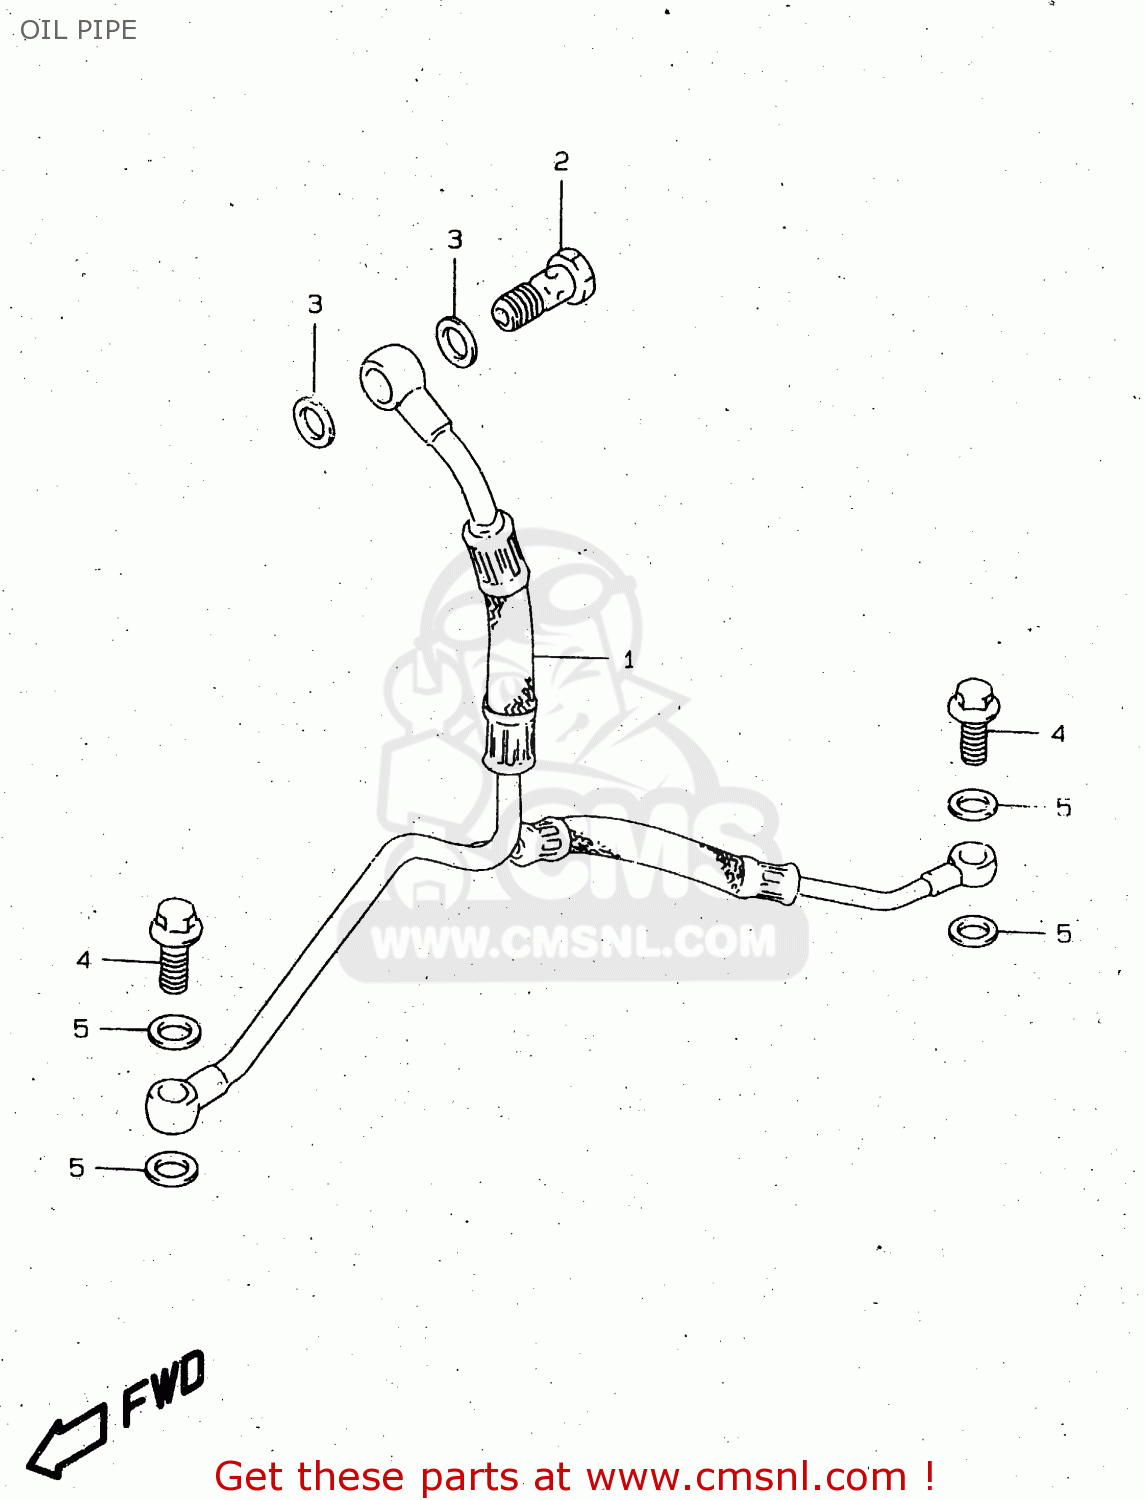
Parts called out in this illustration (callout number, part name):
1	PIPE,T/M & CSHAFT OIL
2	BOLT UNION
3	GASKET(12X17X1) (NAS)
4	BOLT UNION
5	GASKET(10.1X16X1) (NAS)
